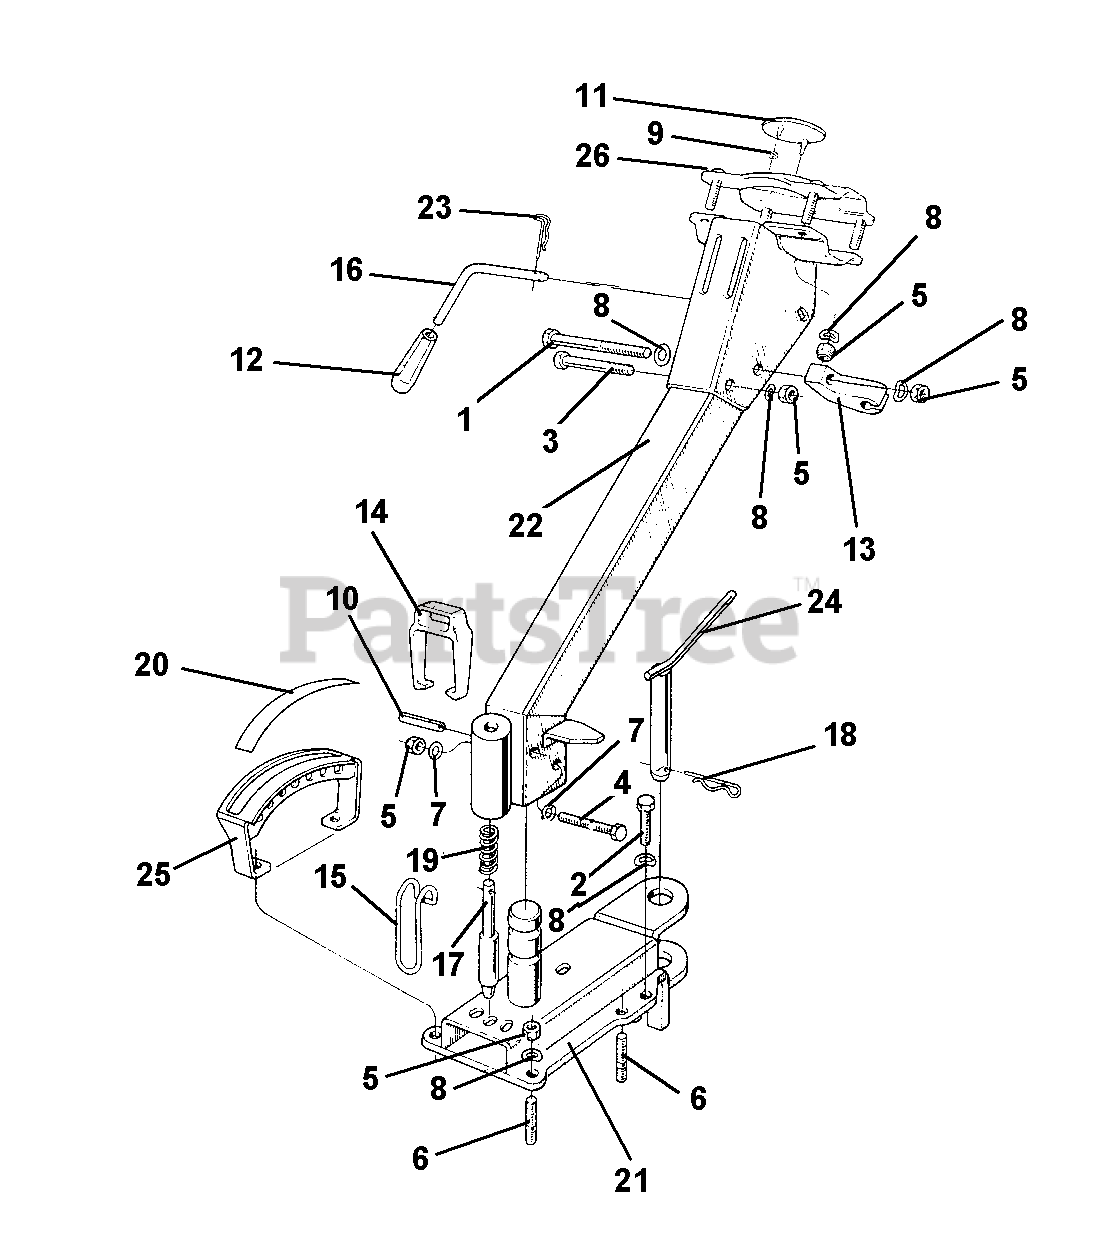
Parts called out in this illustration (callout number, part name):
1	SCREW TE M8 X 100
2	SCREW M8 X 25
3	SCREW M8 X 60
4	SCREW TE M8 X 55
5	NUT, SELF LOCKING M8
6	STUD M8 X 38 X 14 X 20
7	WASHER, FLAT 8.4
8	WASHER, LOCK 8.4
9	WASHER, LOCK FOR PINS
10	SPIRAL PIN 8 X 40
13	SUPPORT CONTROL ROD CUT
14	PASSAGE FOR SHEATH
16	LEVER FOR SECTOR
20	PLATE 5 SPEEDS WALKING TRAC
21	STEERING COLUMN SUPPORT
22	STEERING COLUMN
